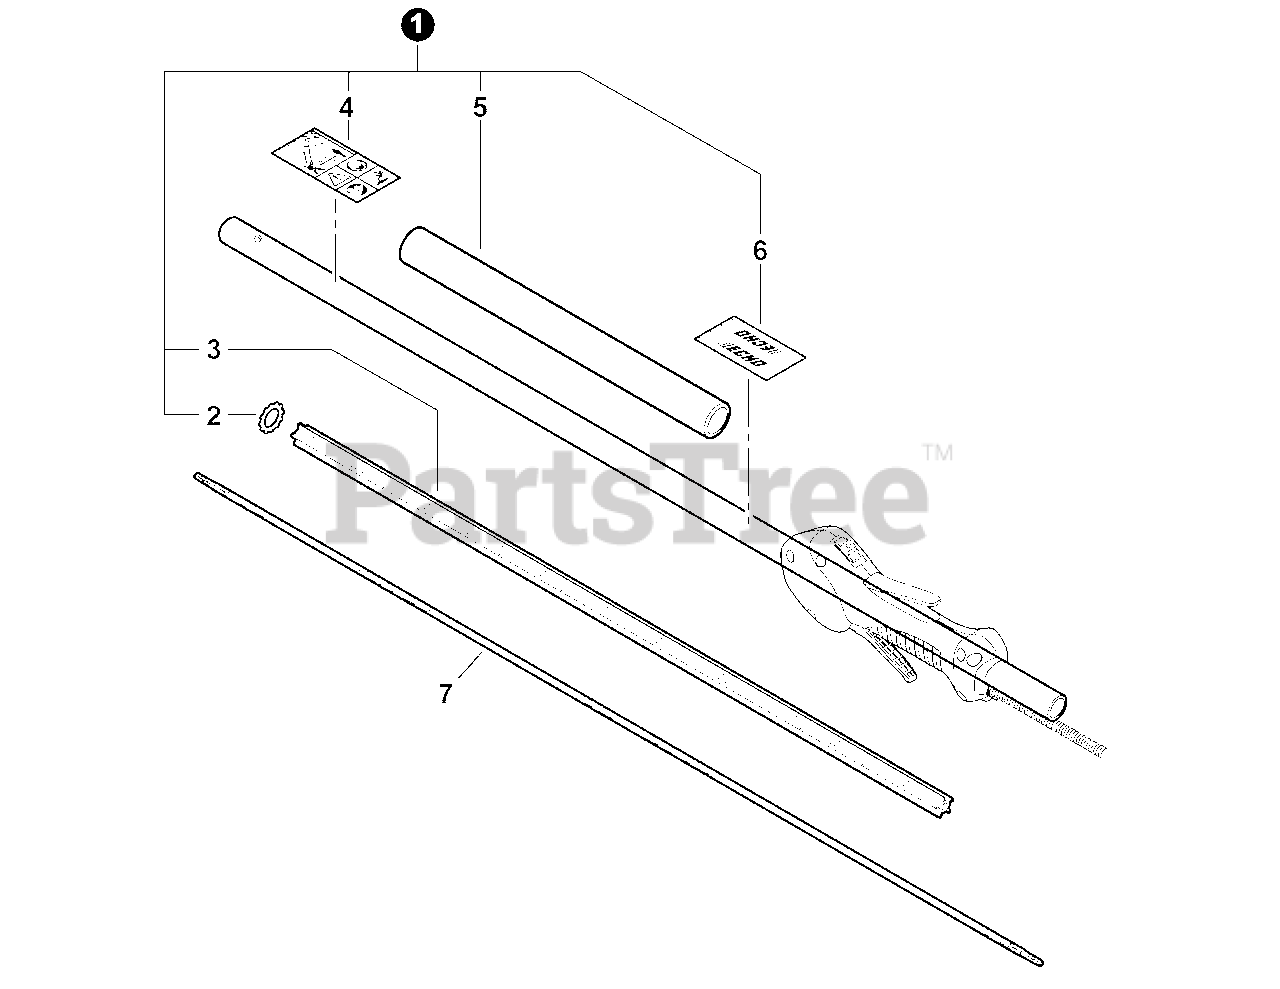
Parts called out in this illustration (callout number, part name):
1	MAIN PIPE ASSY
3	LINER - FLEXIBLE
4	LABEL, CAUTION
5	GRIP, FRONT
6	LABEL, HANDLE LOCATION
7	DRIVESHAFT - FLEXIBLE
